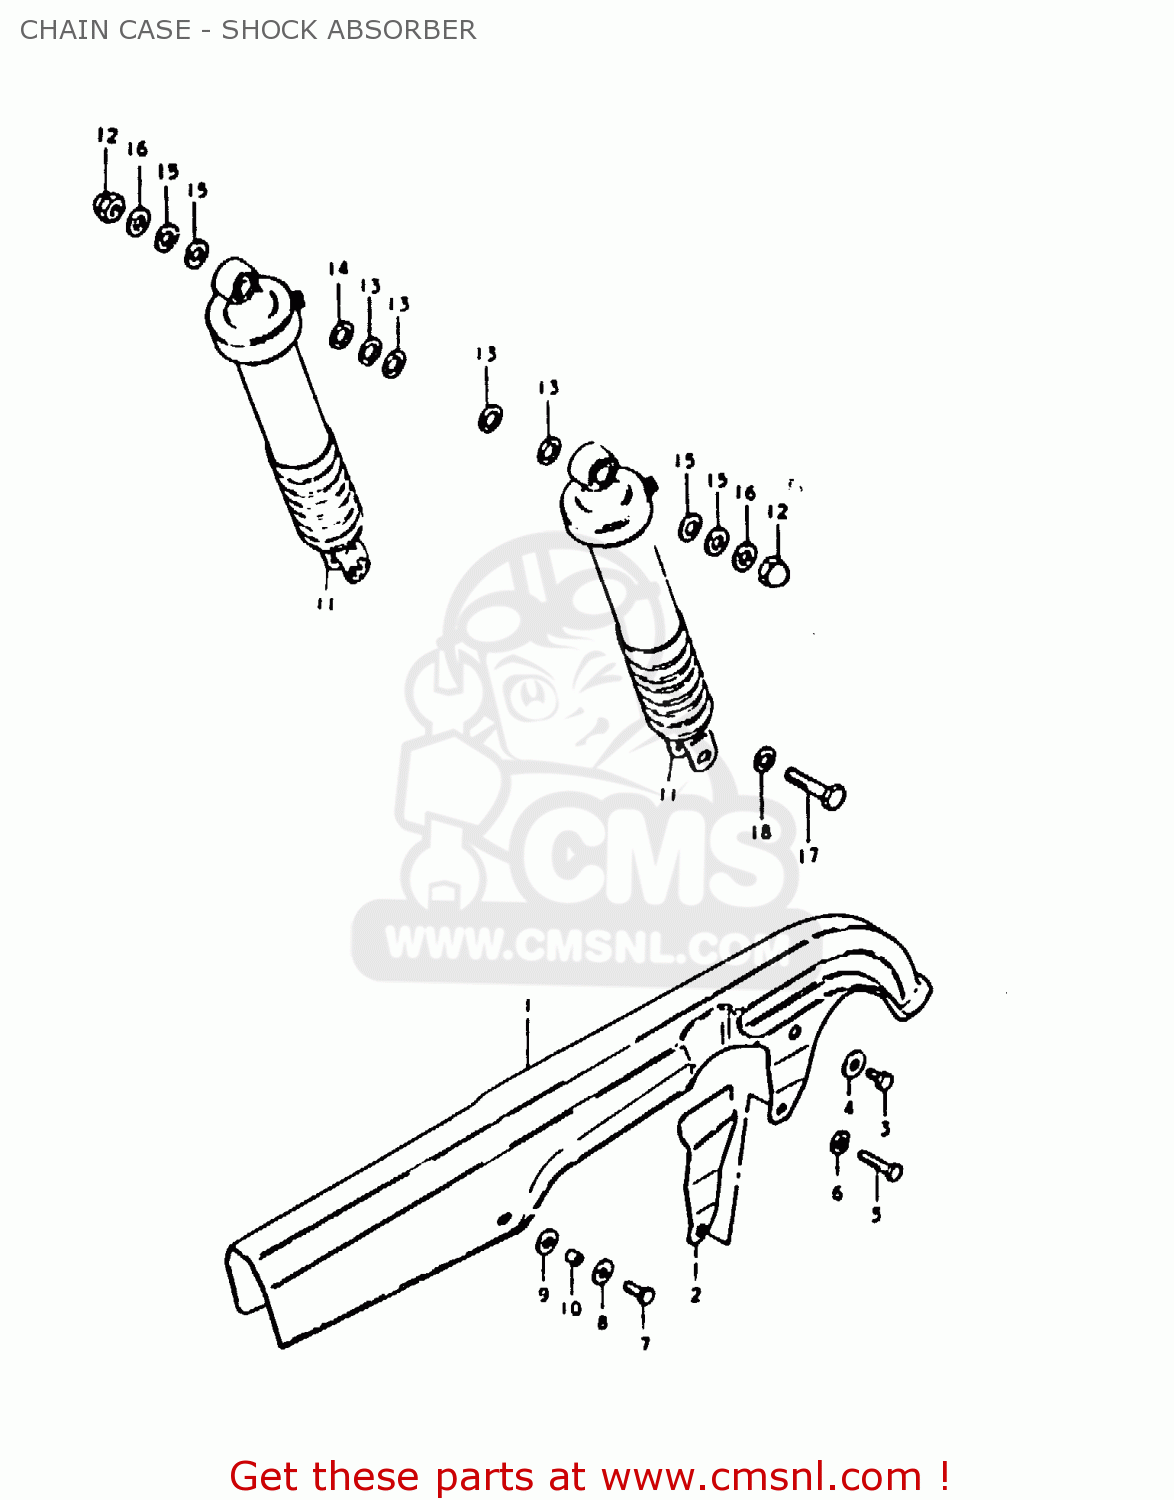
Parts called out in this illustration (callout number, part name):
1	CASE,CHAIN
2	REINFORCEMENT,CHAIN CASE
3	BOLT(6X8)
4	WASHER
5	BOLT
6	LOCK WASHER
7	BOLT
8	WASHER(6.5X18X1)
9	CUSHION
10	SPACER (6.1X8X5.2)
11	SHOCK ABSORBER, REAR
12	NUT, LOWER LH
13	WASHER
14	WASHER (12.5X24X3.2)
15	WASHER
16	WASHER(10.5X24X3.2)
17	BOLT(10X36)
18	WASHER
